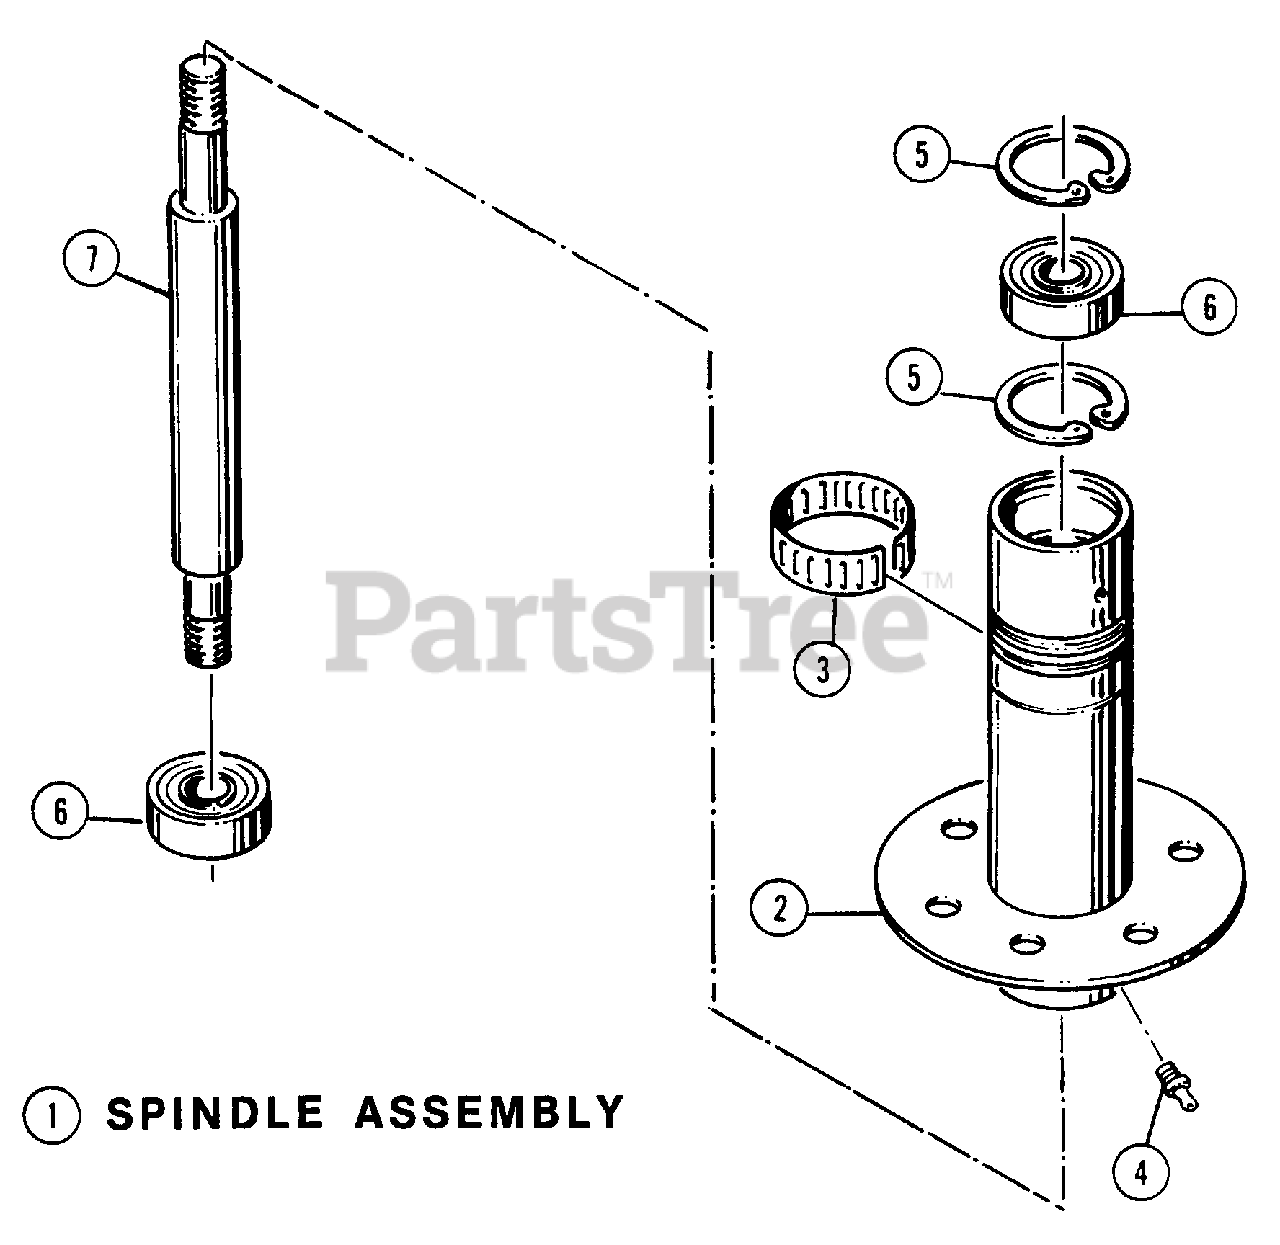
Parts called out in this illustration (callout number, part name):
1	ASSEMBLY, Spindle
2	HOUSING, Spindle
3	RING, Tolerance
4	FITTING, Lube (Press fit for .187 hole-no ball)
5	RING, Retaining
6	BEARING, Ball
7	SPINDLE
